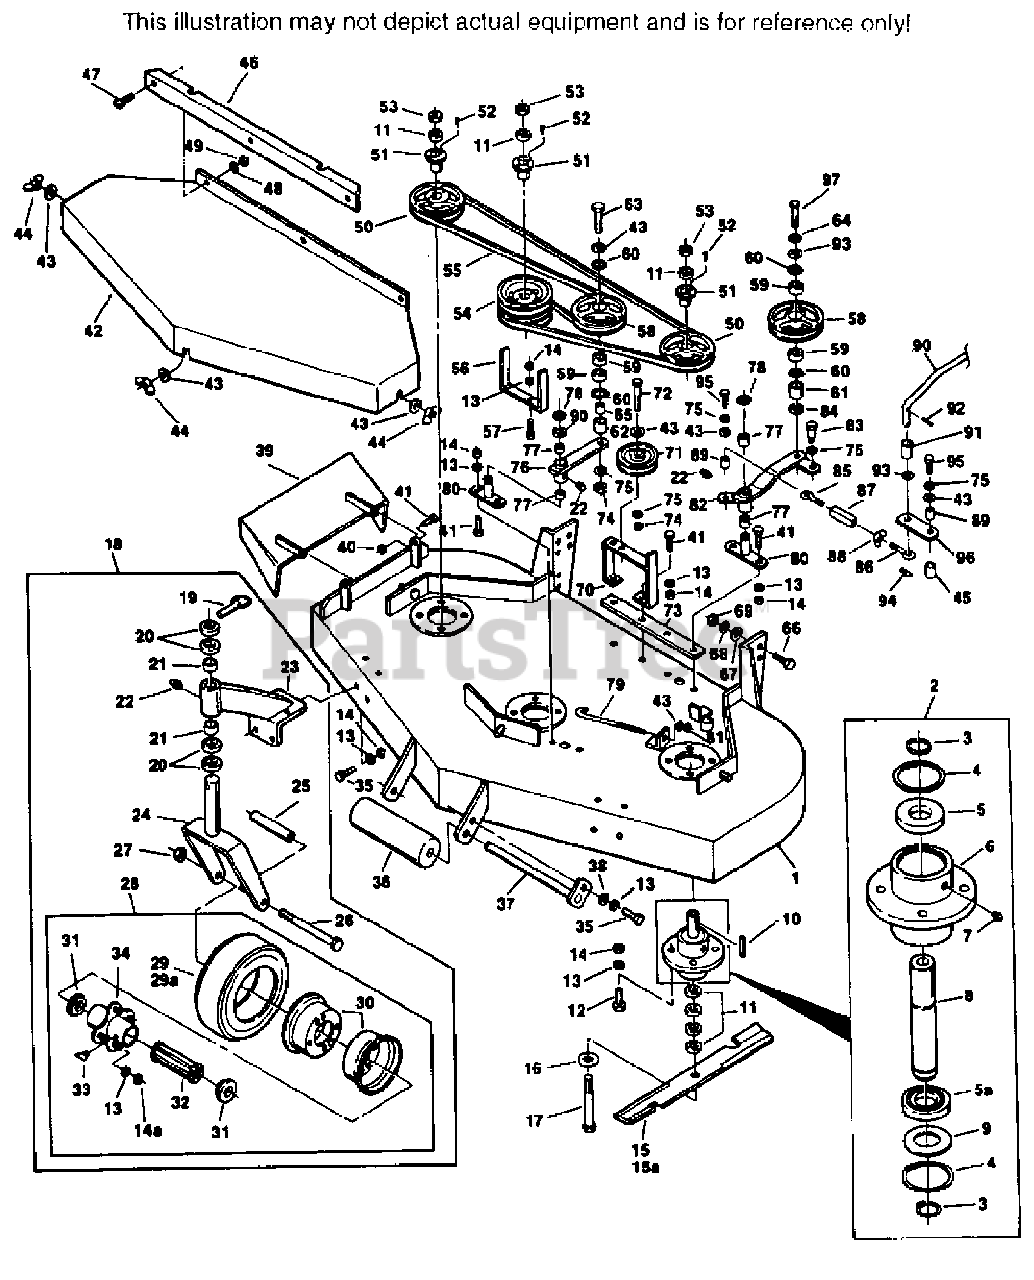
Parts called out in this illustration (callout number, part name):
2	CUTTER SPINDLE ASSY.(INCL. 3-9)
3	RETAINING RING, 1" EXT.-INVERTED
4	RETAINING RING, 2-7/16 INT.-BASIC
5	BEARING, CUTTER SPINDLE
6	SPINDLE HOUSING
7	GREASE FITTING, STR.5/16 SERR.
8	SPINDLE, CUTTER BLADE
9	WASHER, 1-15/16 X 2-13/32 X 16 GA.
10	KEY, 1/4 X 1/4 X 2
11	SPACER, CUTTER BLADE
16	FLAT WASHER, 5/8W
17	HEX HEAD BOLT, 5/8-11 X 9-1/2
18	CASTER ASSY, COMP.(INCL. 19-28)
19	QUICK PIN
20	SPACER, CASTER YOKE, 1/2 LONG
21	BRONZE BEARING
22	GREASE FITTING, STR, 1/4-28
23	SUPPORT ASSY.(INC. 21-22)
24	CASTER YOKE WLD.
25	SLEEVE, CASTER WHEEL BEARING
26	HEX HEAD BOLT, 1/2-13 X 5-1/2
28	WHEEL ASSY.(INCL. 13-14,29-34)
29	TIRE ONLY, CASTER WHEEL
29A	INNER TUBE ONLY, CASTER WHEEL
30	RIM PAIR, CASTER WHEEL
31	RETAINER, BEARING, CASTER WHEEL
32	ROLLER BEARING, CASTER WHEEL
33	GREASE FITTING, 45' 1/4-28
34	HUB ASSY. W/BOLTS, CASTER WHEEL
39	DISCHARGE CHUTE WLD.
40	HEX NUT, 5/16-18 ELASTIC STOP
43	WASHER, 25/64 X 15/16 X 12 GA.
44	WING NUT, 3/8-16
45	SPINDLE SHIELD
46	BELT COVER SKIRT
47	SLOTTED TRUSS HD. MACHINE SCREW,
50	PULLEY(INCL. 51-52)
51	TAPER HUB
58	PULLEY IDLER
59	BEARING
60	RETAINING RING, 1-9/16 INT. BASIC
61	SLEEVE
62	SPACER
67	WASHER, 15/32 X 59/64 X 16 GA.
69	HEX NUT, 7/16-14, ELASTIC STOP
70	IDLER PULLEY SUPPORT
71	PULLEY, BELT GUIDE
73	WASHER, 13/32 X 13/16 X 16 GA.
76	IDLER ARM ASSY.(INCL. 22 & 77)
77	BRONZE BEARING
78	RETAINING RING, 3/4 EXT.-"E"
79	ROD, IDLER PULL, J
80	IDLER PIVOT WLD.
81	HEX NUT, 3/8-16 ELASTIC STOP
82	IDLER ARM ASSY.(INCL. 22 & 77)
83	SHOULDER BOLT
84	SPACER, IDLER
85	EYEBOLT, LH
86	EYEBOLT, RH
87	TURNBUCKLE
88	WING NUT, 5/16-18
89	SLEEVE, CAM CLUTCH
90	BLADE CLUTCH ROD
91	SLEEVE, CLUTCH ROD
93	WASHER, 33/64 X 1 X 16 GA.
94	HAIR PIN, LARGE
96	CAM LINK
97	HEX HD. BOLT 1/2-20 X 2 SPECIAL
